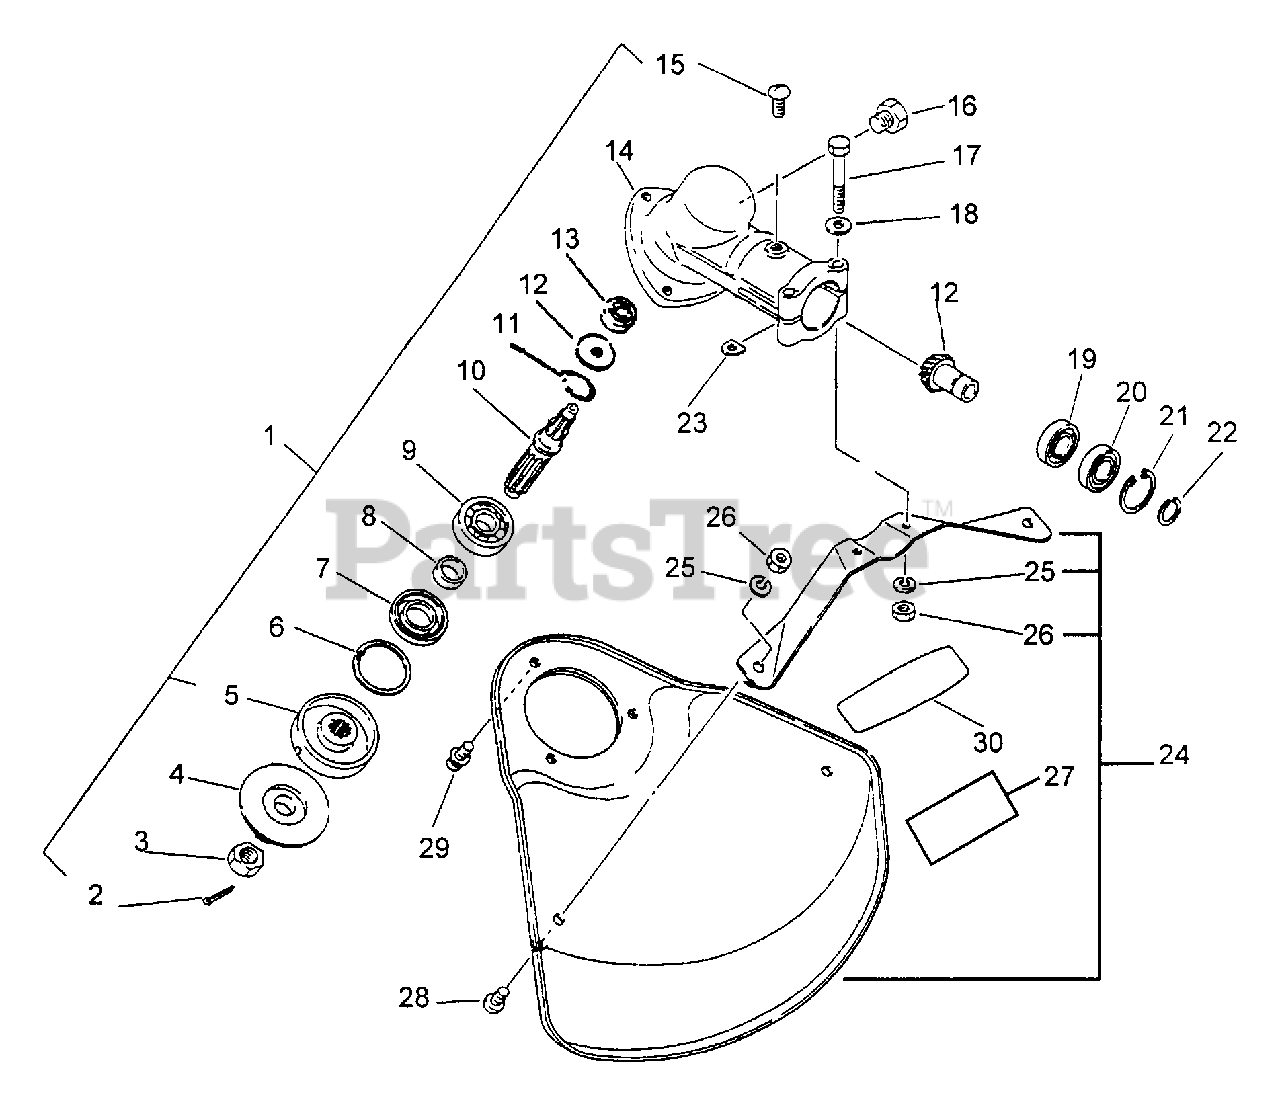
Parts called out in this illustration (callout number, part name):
1	GEAR CASE ASSY
2	PIN, SPLIT - 2X22
3	NUT - 10 -- LEFT HAND
4	ADAPTOR, BLADE - LOWER
5	ADAPTOR, BLADE - UPPER
6	RING, RETAINING - 32
7	SEAL, OIL
9	BEARING, BALL - 6201
10	GEAR - SHAFT
11	RING, RETAINING - 10
12	GEAR SET - BEVEL
13	BEARING, BALL - 609
14	CASE, GEAR
15	SCREW - 5X10
16	BOLT - 8X8
17	BOLT - 5X35
18	WASHER - 5
19	BEARING, BALL - 6900
20	BEARING, BALL - 6900Z
21	RING, RETAINING - 22
22	RING, RETAINING - 12
24	DEBRIS SHIELD KIT
25	LOCKWASHER - 5
27	LABEL - DANGER
28	SCREW - 5X8
29	SCREW - 5X10
30	LABEL - ECHO
